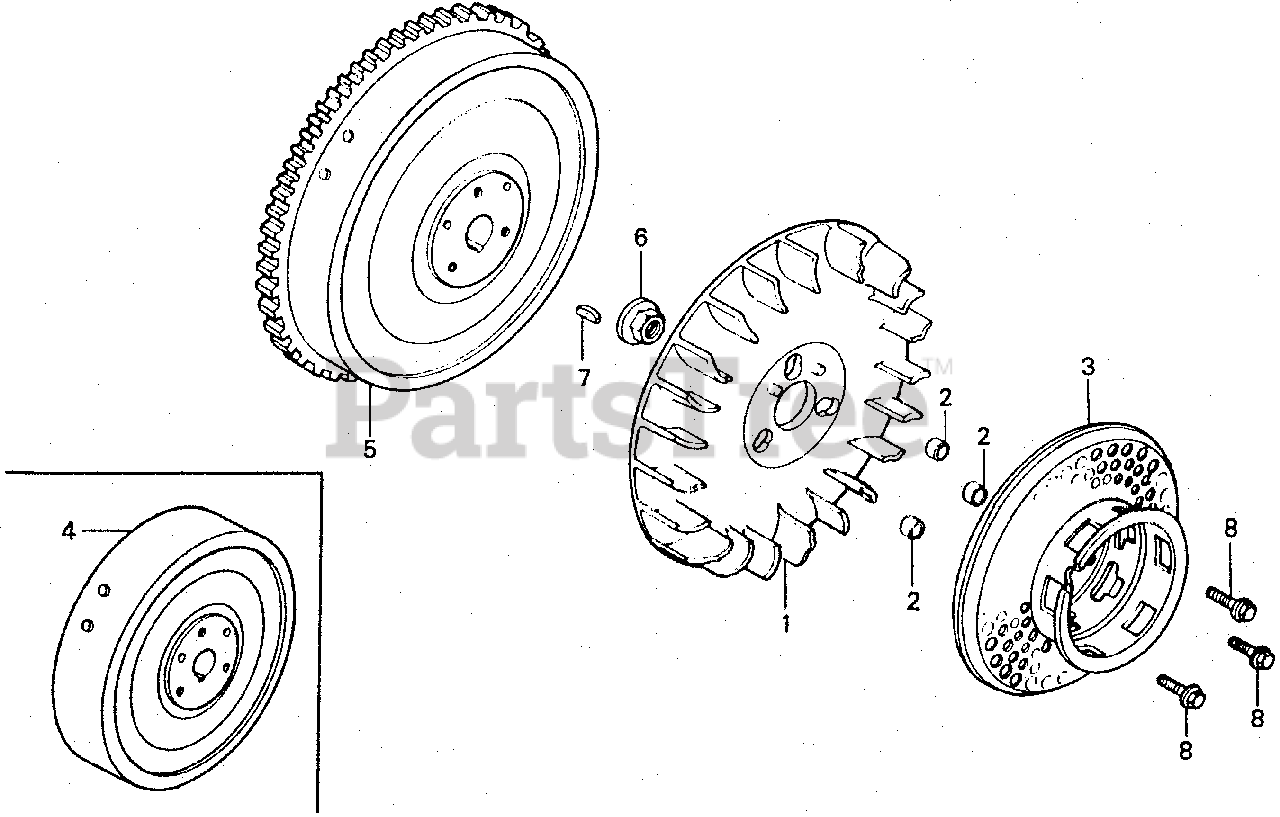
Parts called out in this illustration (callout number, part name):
1	FAN, COOLING
2	COLLAR, FAN
3	PULLEY, STARTER
5	FLYWHEEL (BREAKER+STARTER)
6	NUT, SPECIAL (16MM)
7	KEY, SPECIAL WOODRUFF (25X18)
8	BOLT, FLANGE (6X16)
